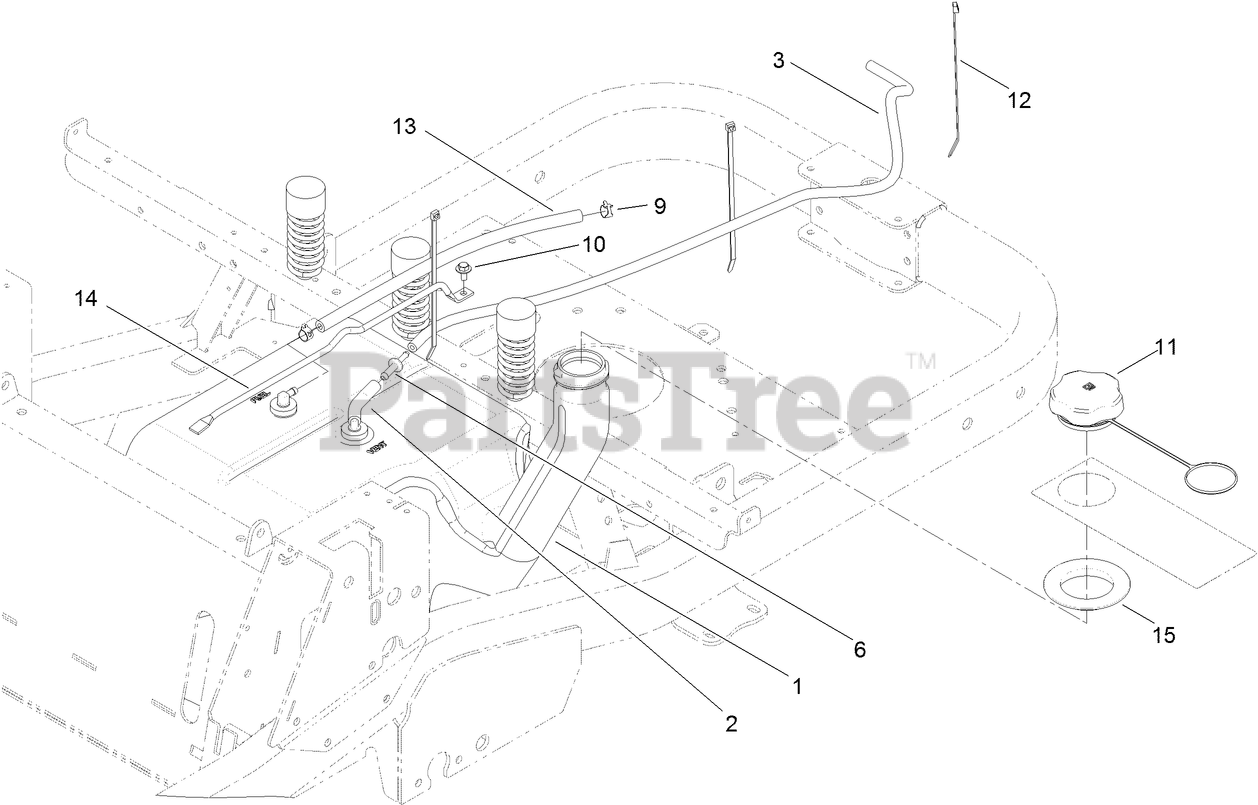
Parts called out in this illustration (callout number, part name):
1	FUEL TANK ASM
2	HOSE-FUEL
3	HOSE-FUEL
6	ADAPTER-ORIFICE
9	CLAMP-HOSE
10	SCREW-HHFTF
11	CAP-FUEL
12	TIE-CABLE
13	HOSE-FUEL
14	ROD-TANK, GAS
15	SEAL-TANK
